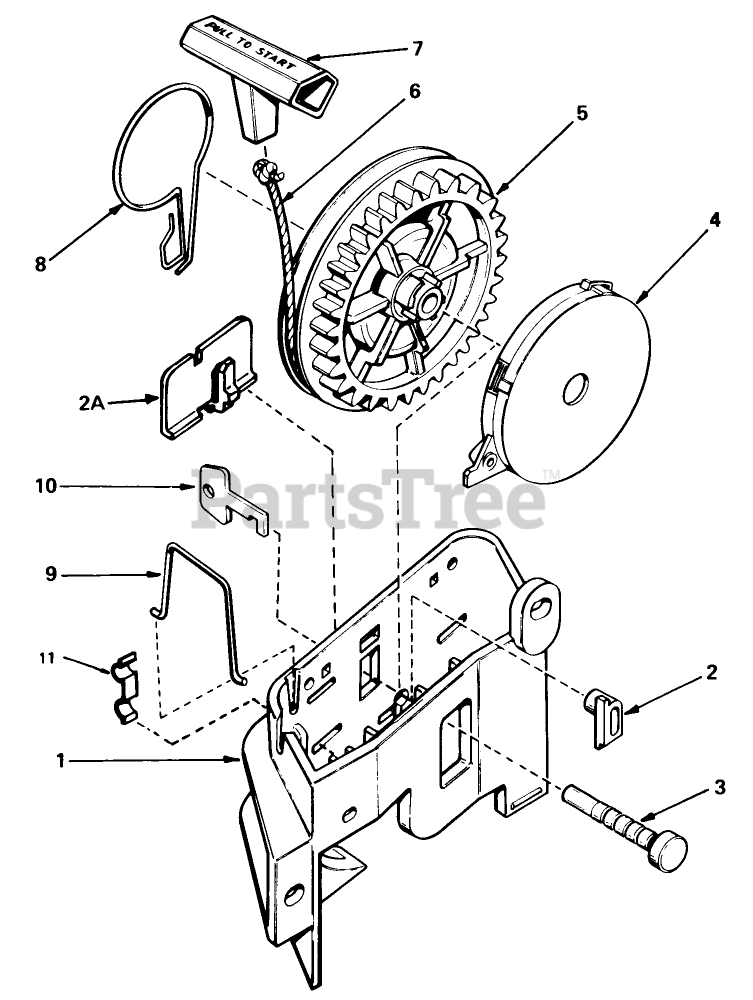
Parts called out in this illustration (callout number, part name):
1	Bracket Starter
2	Pawl, Locking Not used on all engine models)
2A	Clip, Starter Bracket (Used On Starters Not Equipped With Pawl, Ref. No. 2)
3	Pin-Pulley
4	Spring Assy., Rewind (Incl. Ref. #3)
5	Pulley
6	Rope Starter (Length 65" 9/64" Dia.)
7	Handle-Starter
8	Brake
9	Clip-Rope
10	Key (Not Used On All Engine Models
11	Washer-Thrust
